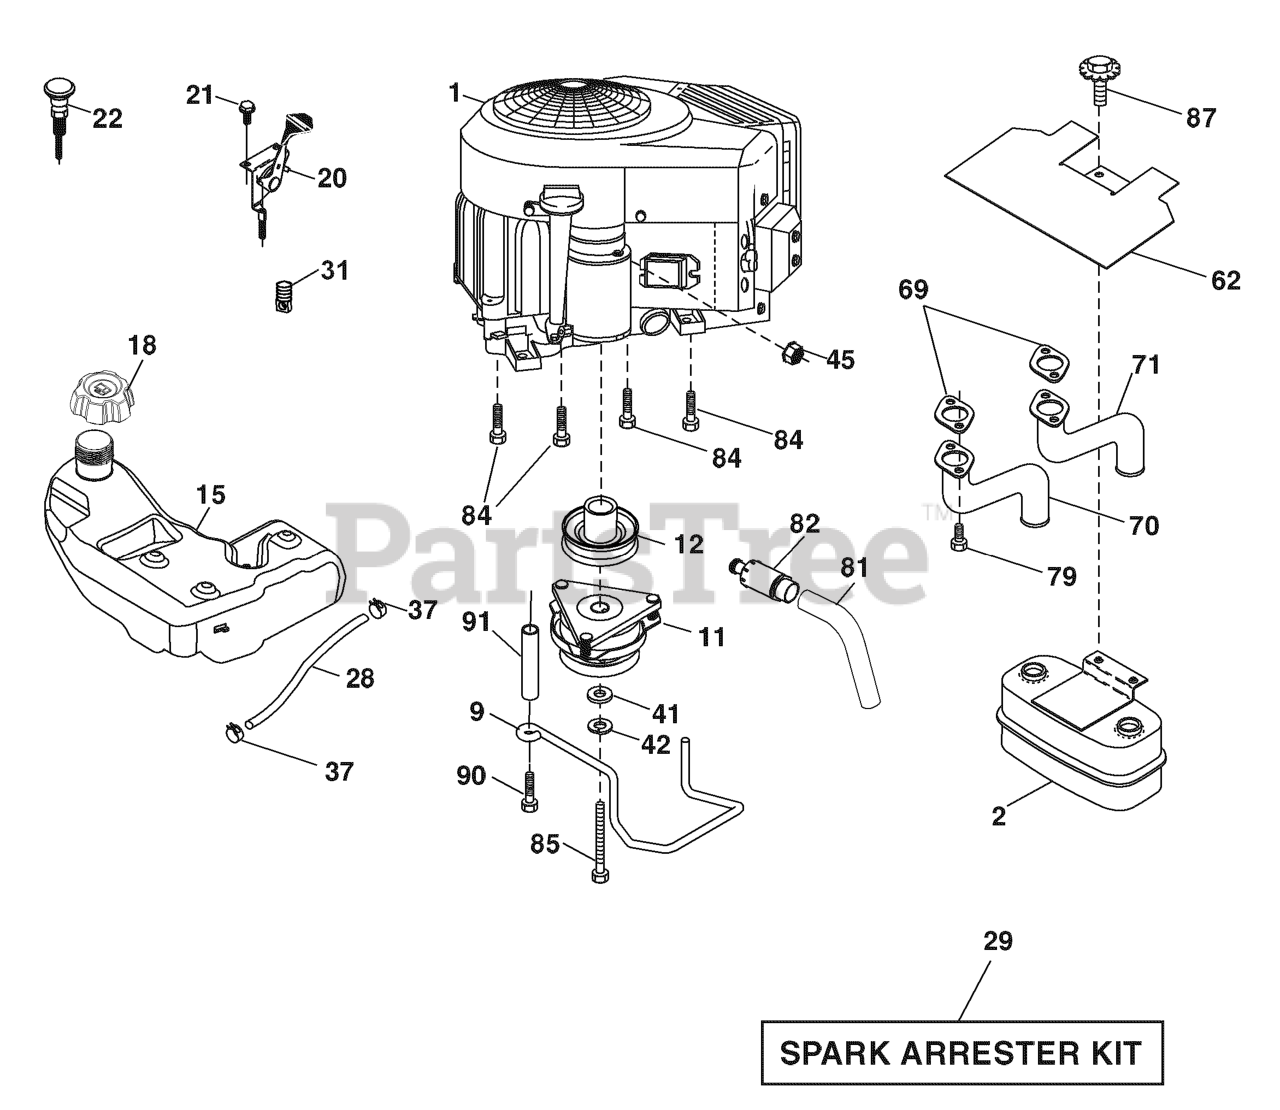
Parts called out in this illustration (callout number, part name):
2	MUFFLER.TWIN.CYL.LOW.TONE
9	KEEPER.BELT.ENGINE.4.2
11	CLUTCH MZ ZTR GT.48/54"1.125"
12	PULLEY ENGINE
15	TANK.FUEL.4GAL
18	CAP.FUEL.TANK.3"GREY
20	THROTTLE CABLE
21	SCREW.#10 X 0.750.BOS
22	CONTROL.CHOKE.ERGO.PUSH-IN.BLA
28	LINE.FUEL.64"REAR.EMIS
29	KIT.SPARK ARRESTOR 794945 B&S
37	HOSE CLAMP
42	LOCKWASHER
45	NUT
62	RP SHIELD HEAT MUFFLER
69	GASKET.MUFFLER
70	RP.EXHAUST.TUBE.LH.BS/TWIN
71	EXHAUST.TUBE.RH.BS/TWIN
79	SCREW.SOCKET.HEAD.5/16-18
81	TUBE, DRAIN OIL ASM.
82	PLUG DRAIN OIL EASY
84	SCREW.3/8-16
85	BOLT HEX 7/16-20 X 3.75 GR. 5
87	BOLT.5/16-18UNCX1.W/SEMS.BLK
90	SCREW 3/8-16X1
91	BUSHING.1.375OD
